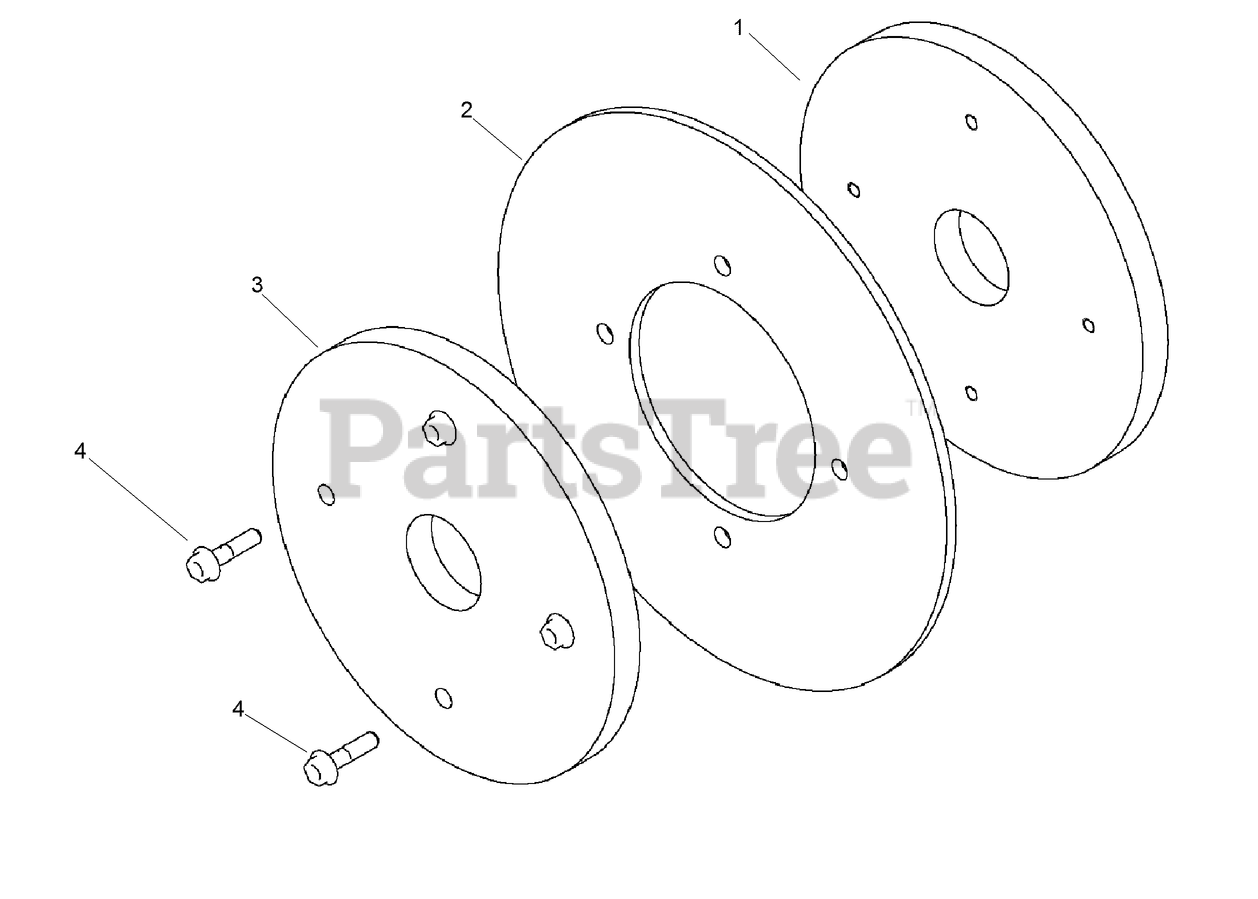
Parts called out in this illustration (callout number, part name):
2	SEAL-RUBBER, FOLLOWER
3	PLATE
4	SCREW, METRIC FLANGE w/BODY-M6 x 25
